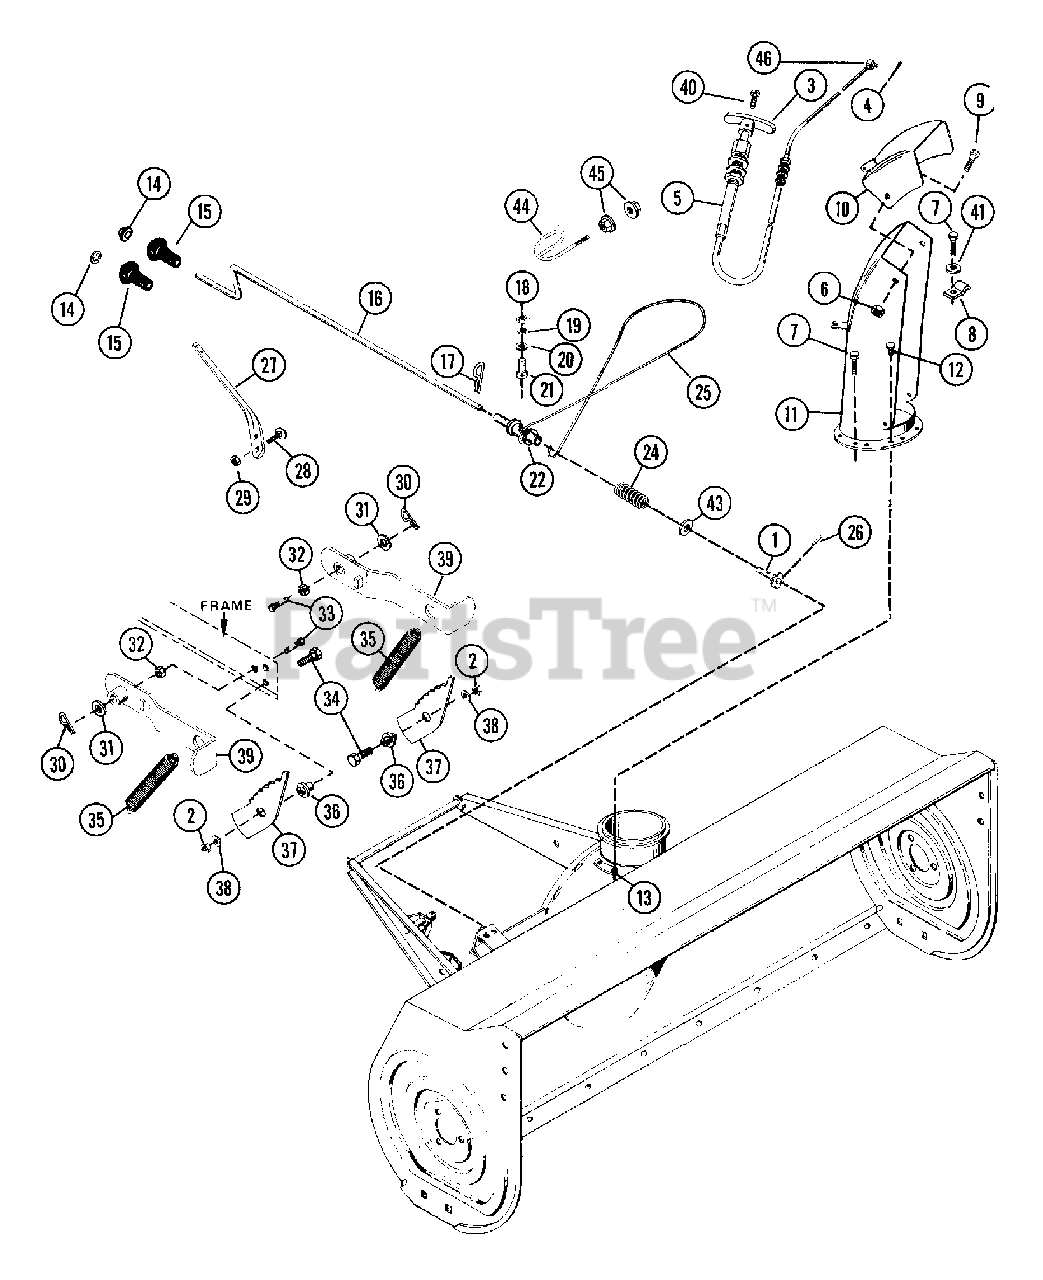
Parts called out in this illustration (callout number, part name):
1	DISC ASSEMBLY
2	NUT-LK .312-18 GR A PL
3	TEE HANDLE
4	PIN-COTR .09X.75 PL
5	CONTROL CABLE
6	NUT-LK-CTR .375-16 GR A PL
7	SCR-TAP 10-24X.75 HWH PL TR
8	CABLE CLAMP
9	BLT-HEX .38-16X.75 PL GR2
10	DEFLECTOR W/DECAL
11	DISCHARGE CHUTE
12	SCR-TAP 10-24X.484 HWH TR
13	CHUTE CLAMP
14	CAP, 3/8 ROD YWZC
14	RG-RTNG-EXT .500X.015
16	CRANK - CHUTE CONTROL
16	CHUTE CONTROL CRANK
17	PIN-HAIR INT .08X.38X1.42 YWZC
18	NUT-HEX .250-20 PL
19	WSHR-LK .313X.062
20	WSHR-FL-STL.281X.62X.065 PL
21	BLT-RDHDSQNK .25-20X.62 PL
22	SPOOL
24	SG-COMP .054X.75X1.6
26	PIN-ROLL .188X1.00
27	CHUTE SUPPORT
28	BLT-RDHDSQNK .38-16X1.0 PL
29	NUT-LK-CTR .375-16 GR A PL
30	PIN-HAIR INT .08X.18X1.18
31	WSHR-FL-STL .458X.750X.06 PL
32	NUT-LK-CTR .50-13
33	STUD-WEIGHT
34	BLT-HEX .31-18X1.25 PL GR2
35	SG-TENS .188X1.50X8.5 WLD 57
36	SPACER .323X.498X.531X1.000
37	SPRING ASSIST CONTROL
38	WSHR-FL-STL .38X.875X.083 PL
39	SPRING ARM
40	SCR-MCH 10-32X.50 SLPAN SS
40	SCR-MCH 8-32X.75 SLPAN PL
41	WSHR-FL-STL .219X.500X.049 PL
43	WSHR-FL-STL .640X1.005X.062 PL
44	CABLE SUPPORT
45	NUT-LK-FLG .250-20 PL
